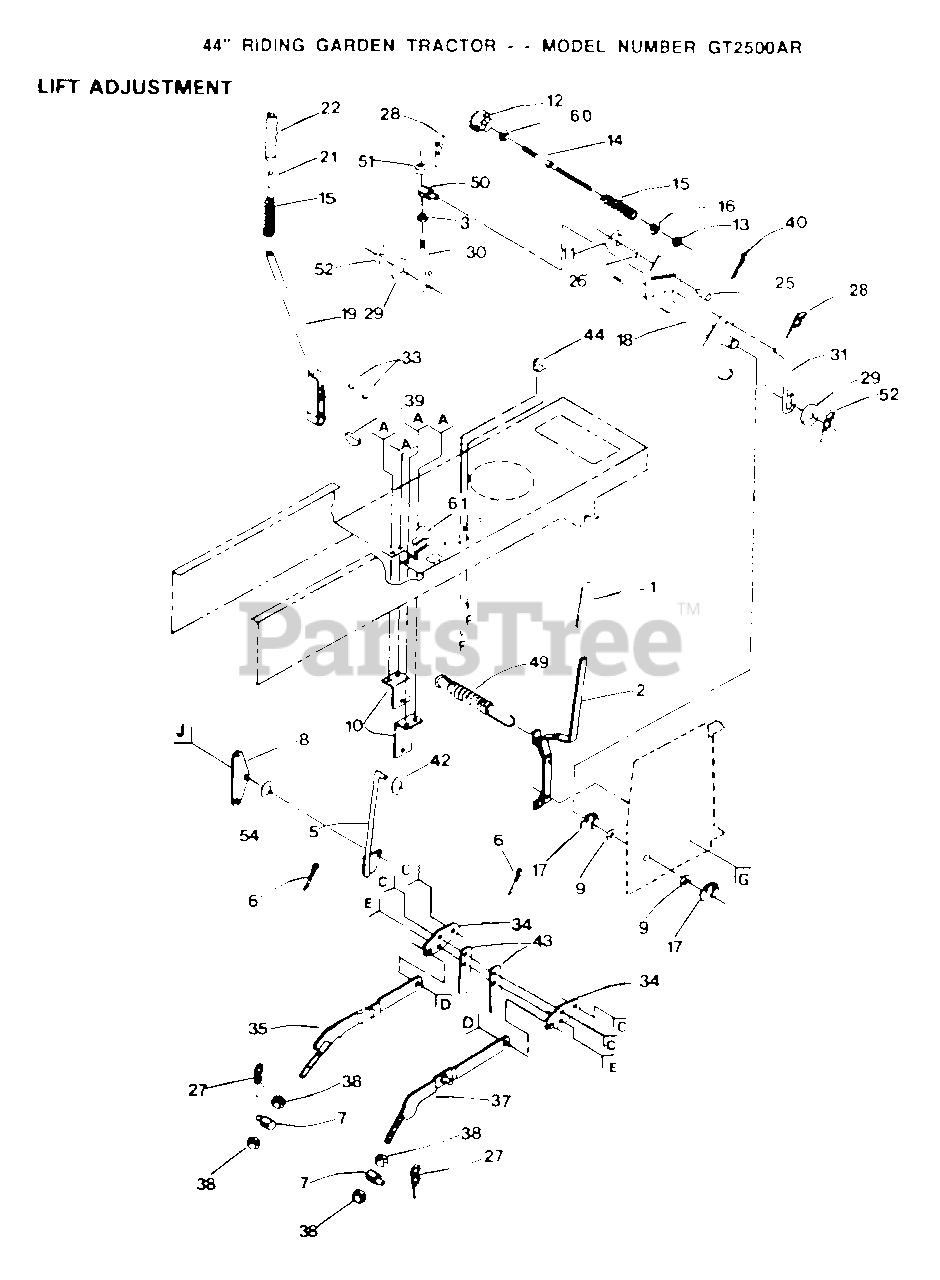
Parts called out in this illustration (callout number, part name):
5	ROD ASSEM YT
6	COTTER PIN
8	"T, BELLCRANK"
9	WASHER
10	"BRKT,BELLCRAN T"
11	KLIP RING
13	NUT T
14	ROD LIFT LT
15	SPRING T
16	WASHER
17	E-RING
22	GRIP
23	SCREW LT
25	TRUNION LT
26	WASHER
27	SPRING H
30	PIVOT PIN T
31	LIFT LINK LT
34	"BRACKET, SUSPE T"
35	LH SUSP ARM ASM
37	RH SUSP ARM ASM
38	NUT
41	NUT
42	WASHER
43	UPSTOP
44	BRACKET LT
49	"SPRING.EXT.8.5"""
51	NUT
52	SPRING.RETAINER
54	WASHER
57	BOLT LT
